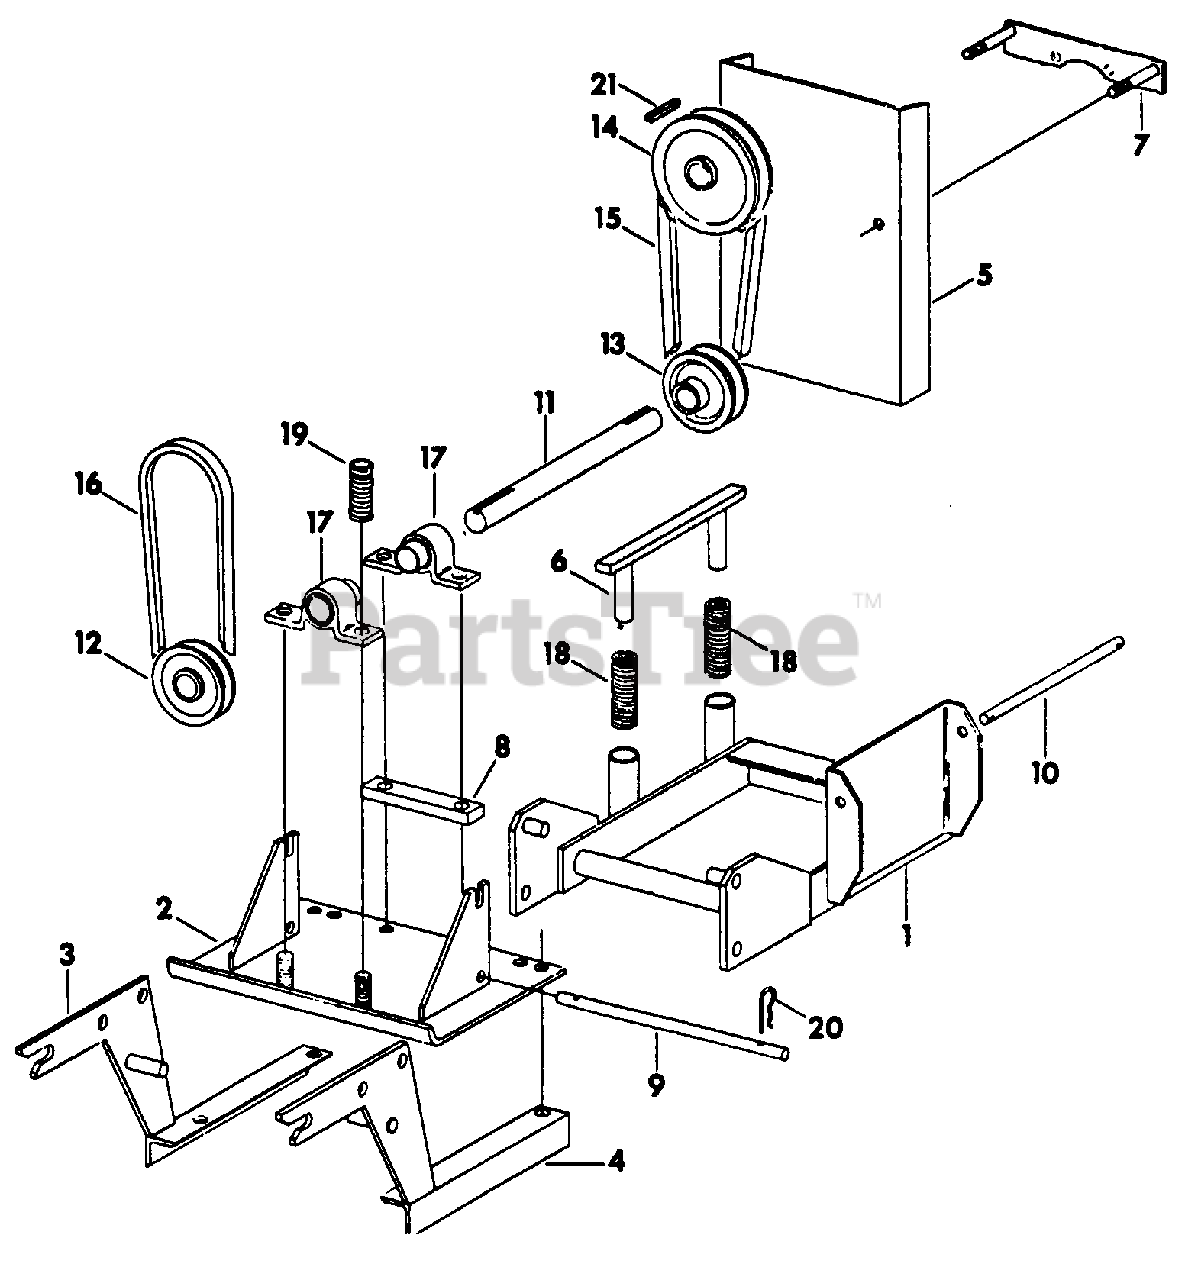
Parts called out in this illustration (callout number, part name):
2	Plate, Brg
3	Bracket, Mounting LH
4	Bracket, Mounting RH
6	Support, Belt Tensioning
7	Bracket, Shield
9	Pin, Frame Mounting
10	Pin, Shredder Mounting
11	Shaft, Drive
13	Pulley, 4 In. Diameter
15	V-Belt, 1/2 Top Width X 42 In. Outside Circumference
16	V-Belt, 1/2 Top Width X 30 In. Outside Circumference
17	Bearing, Pillow Block Ball
20	Pin, Quick Attachable
21	Key, 1/4 X 1 Sq Parallel
